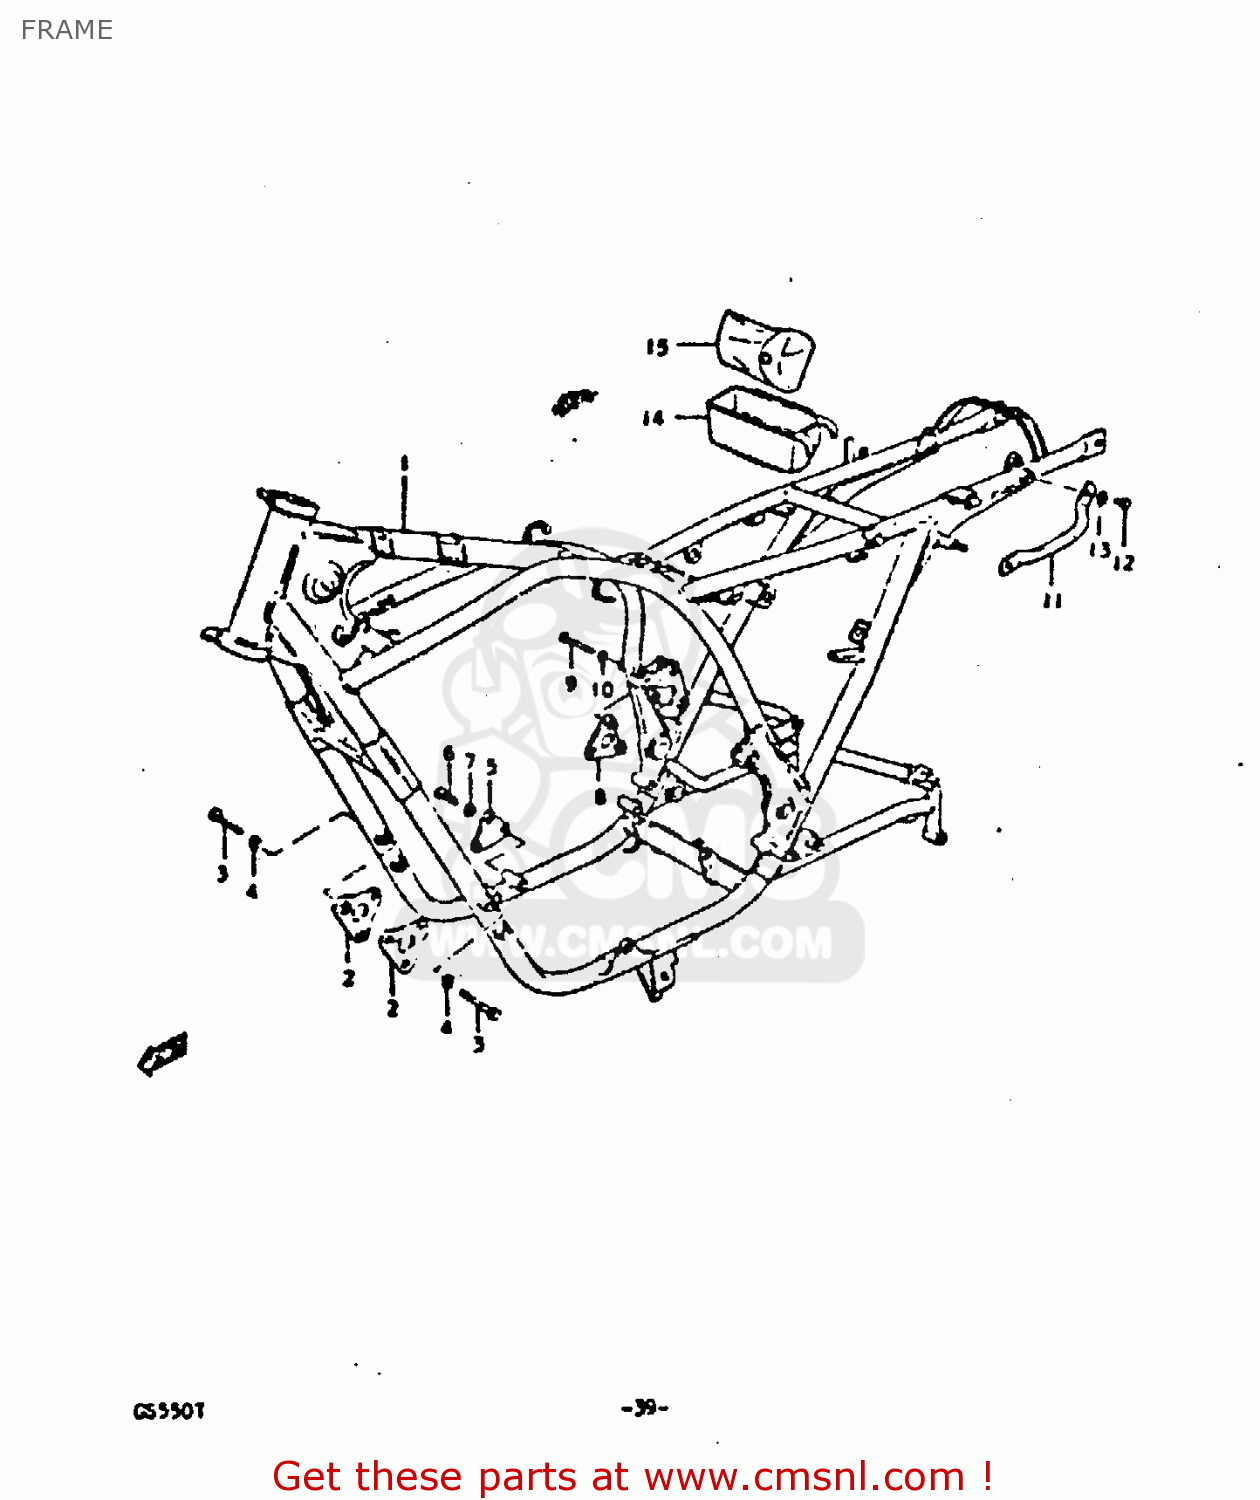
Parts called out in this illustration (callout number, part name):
1	FRAME
2	PLATE,ENGINE MOUNTING
3	BOLT
4	LOCK WASHER
5	PLATE,ENGINE MOUNTING
6	BOLT
7	LOCK WASHER
8	PLATE,ENGINE MOUNTING
9	BOLT 8X55
10	LOCK WASHER
11	GRIP,FRAME HANDLE
12	BOLT
13	WASHER
14	HOLDER,TOOL
15	TOOL SET
